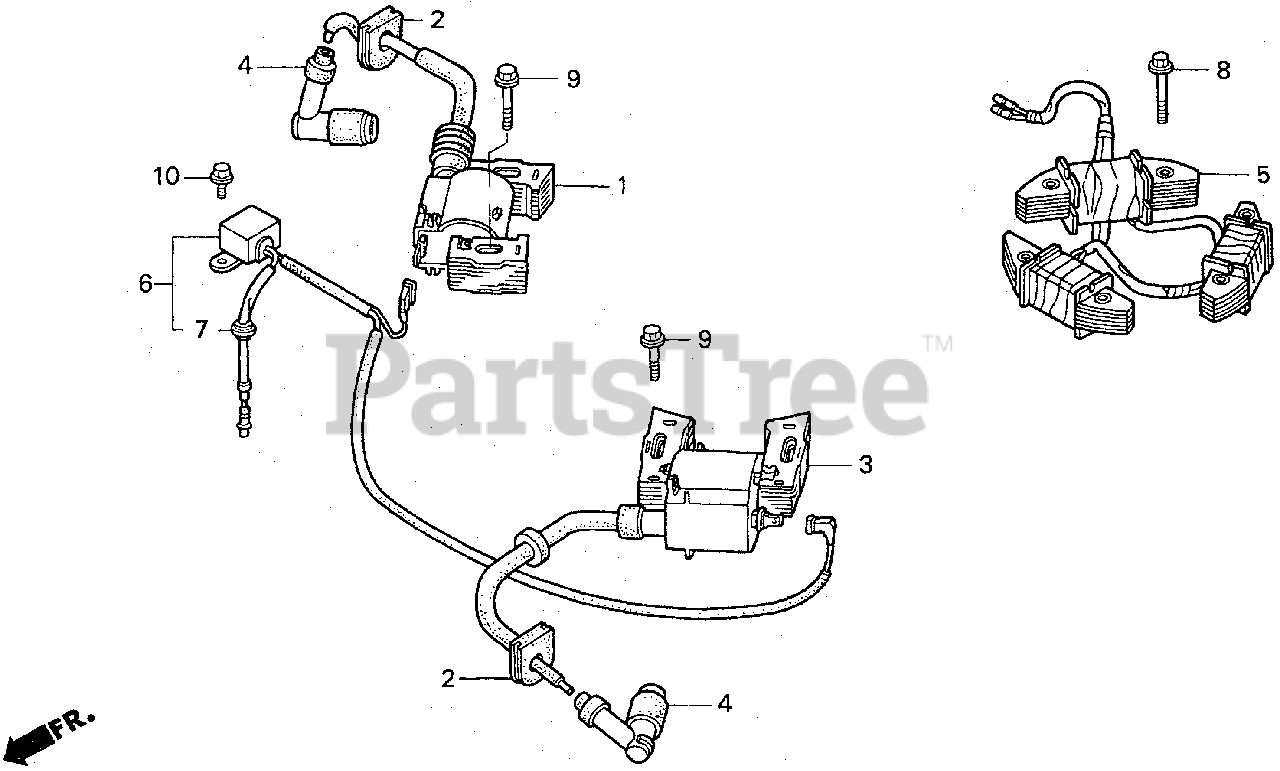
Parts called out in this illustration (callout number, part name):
1	COIL ASSY., R. IGNITION
2	GROMMET, IGNITION WIRE
3	COIL ASSY., L. IGNITION
4	CAP ASSY., NOISE SUPPRESSOR
5	COIL ASSY., CHARGE (12V/20A)
6	DIODE ASSY., ENGINE STOP
7	GROMMET, TOOL
8	BOLT, FLANGE (6X32)
9	BOLT, FLANGE (6X25)
10	BOLT, FLANGE (6X8)
